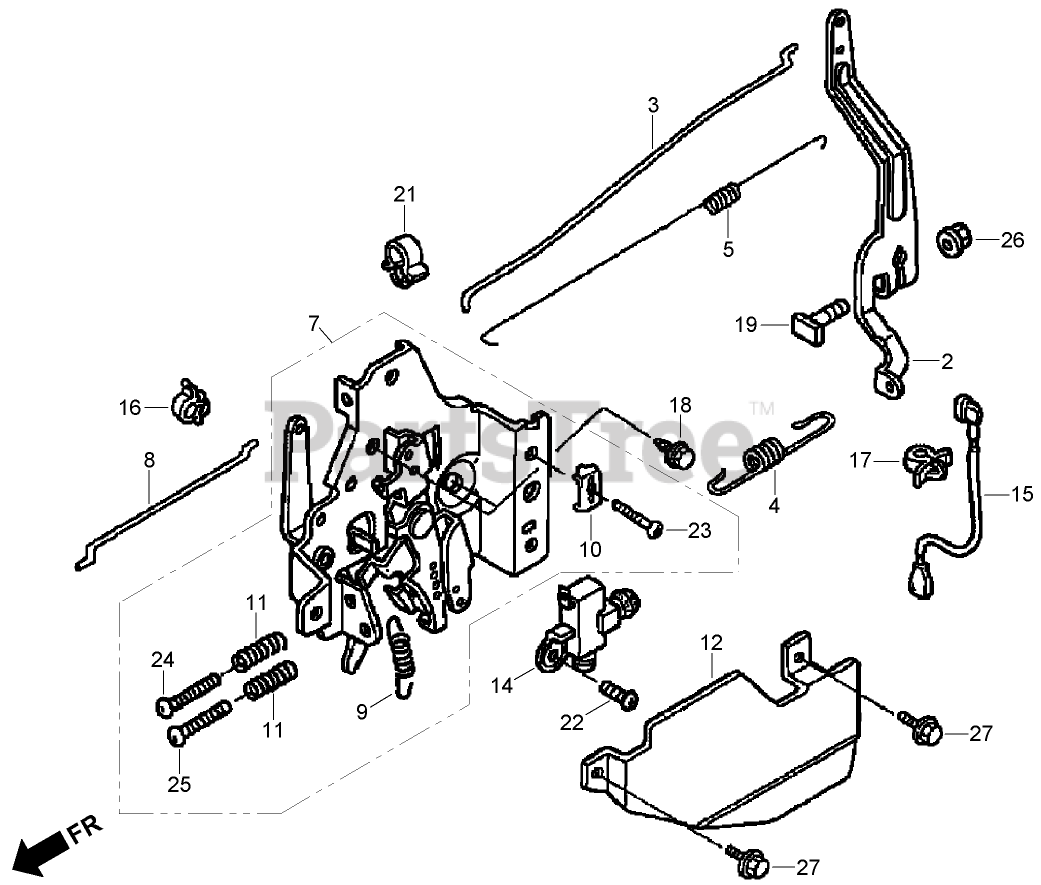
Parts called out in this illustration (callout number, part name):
2	Arm-Governor
3	Rod-Governor
4	Spring-Governor (STD)
5	SPRING-RETURN, THROTTLE
7	CONTROL ASM
8	Rod-Choke
9	Spring-Lever
10	Holder-Cable
11	SPRING-ADJUSTING, CONTROL
12	Protector-Control
14	ENGINE STOP SWITCH ASM
15	WIRE-SWITCH, STOP
16	HOLDER-WIRE, STOP SWITCH
17	CLAMP-PIPE, BRAKE
18	BOLT-FLANGE (6X12) (C T200)
19	BOLT-ARM, GOVERNOR
21	CLIP-HARNESS, WIRE
22	Screw-Pan (4X8)
23	Screw-Pan (5X16)
24	Screw-Pan (5X20)
25	Screw-Pan (5X28)
26	NUT-FLANGE (6 mm)
27	Bolt-Flange (6X10)
